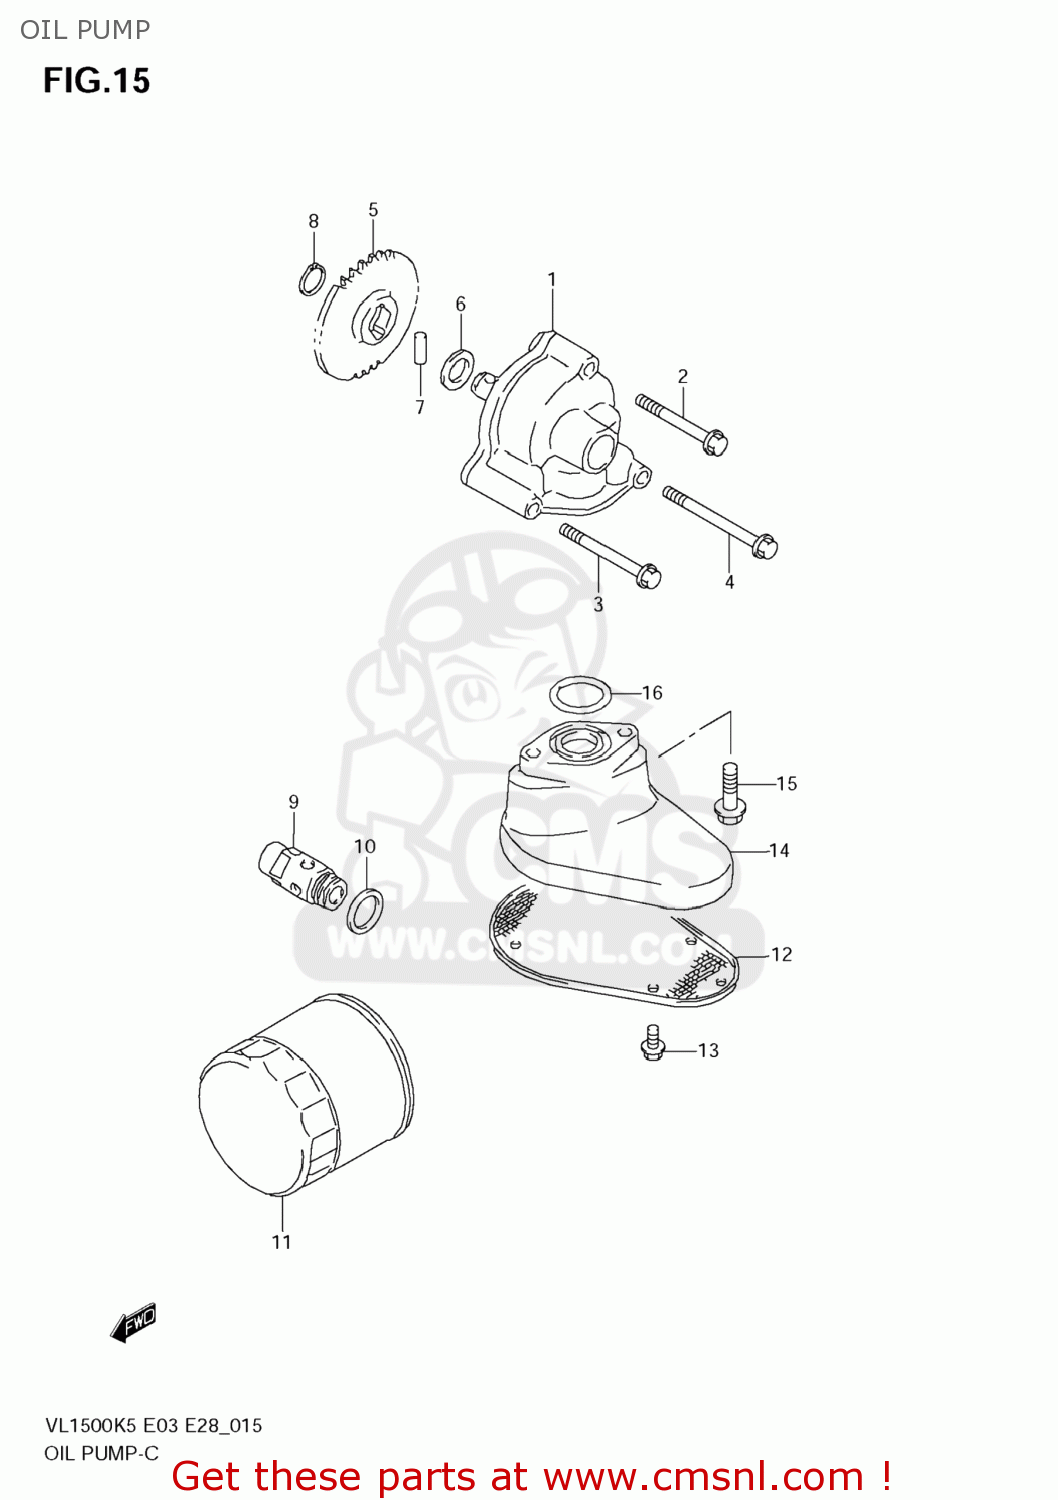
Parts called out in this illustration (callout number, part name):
1	PUMP ASSY,ENGINE OIL
2	BOLT
3	BOLT
4	BOLT
5	GEAR,OIL PUMP DRIVEN
6	SHIM(12X20X0.5)
7	PIN(5X18)
8	CIRCLIP,12 MM
9	VALVE ASSY,OIL RELIEF
10	GASKET(16X22X2) (NAS)
11	FILTER ASSY,EN
12	STRAINER,ENGINE OIL
13	BOLT
14	HOLDER,OIL STR
15	BOLT
16	O RING(D:3.1,ID:22.7)
